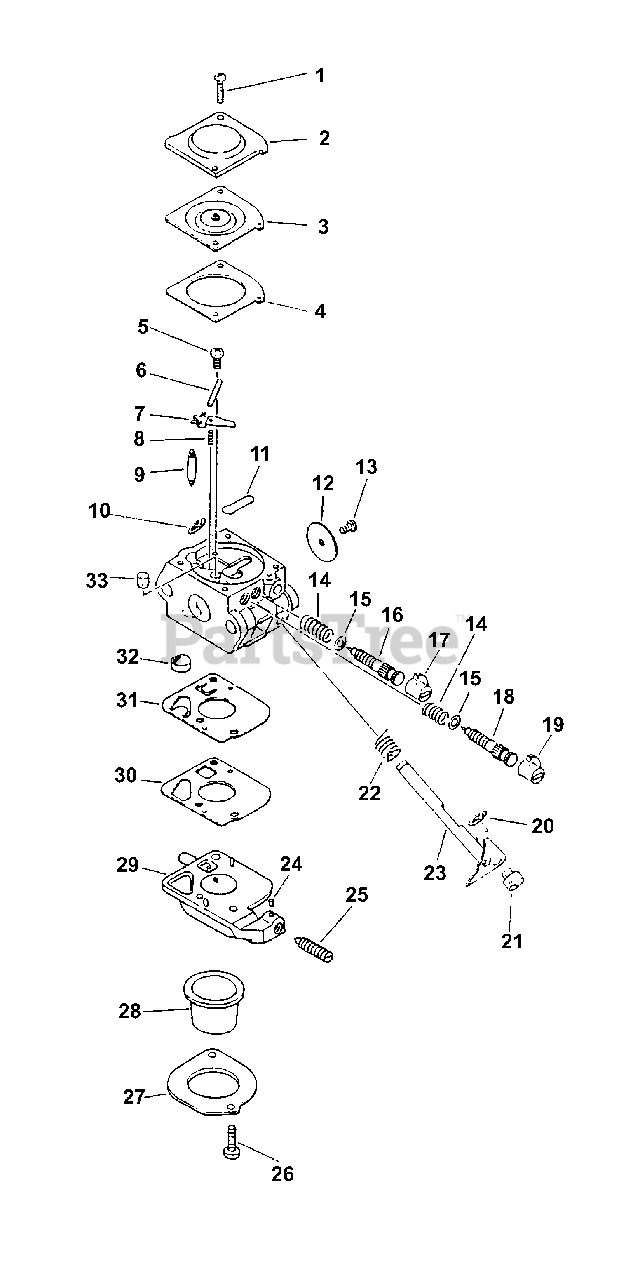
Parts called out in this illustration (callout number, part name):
2	COVER, METERING DIAPHRAGM
3	DIAPHRAGM
4	GASKET, DIAPHRAGM
6	PIN, METERING LEVER
7	LEVER, METERING
8	SPRING
9	VALVE, NEEDLE
11	PLUG, WELCH
12	VALVE, THROTTLE
14	SPRING, NEEDLE
16	NEEDLE, IDLE
17	CAP, LIMITER - WHITE
18	NEEDLE, HIGH SPEED
19	CAP, LIMITER
22	SHAFT, THROTTLE
23	SPRING, THROTTLE RETURN
24	PIECE, FRICTION
25	SCREW, IDLE ADJUST
27	RETAINER
28	BULB, PURGE
29	BODY ASSY, PURGE
30	GASKET, PUMP
31	DIAPHRAGM, PUMP
32	STRAINER
33	NOZZLE, CHECK VALVE
